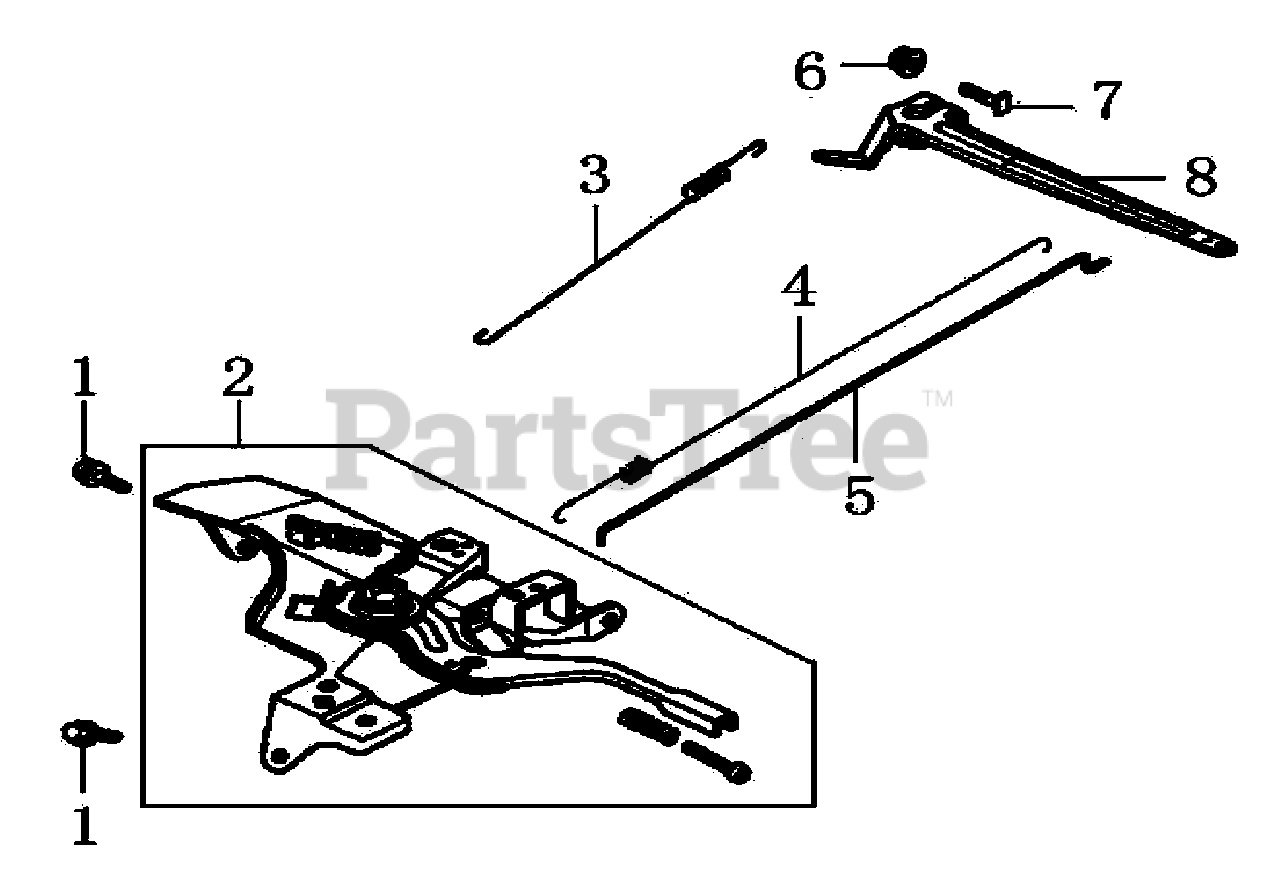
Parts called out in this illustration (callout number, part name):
1	BOLT, FLANGE 6X12
2	CONTROL ASSY.
3	SPRING, CABLE RETURN
4	SPRING, THROTTLE RETURN
5	ROD, GOVERNOR
6	NUT, FLANGE M6
7	BOLT, QUADRATE HEAD
8	ARM, GOBERNOR
